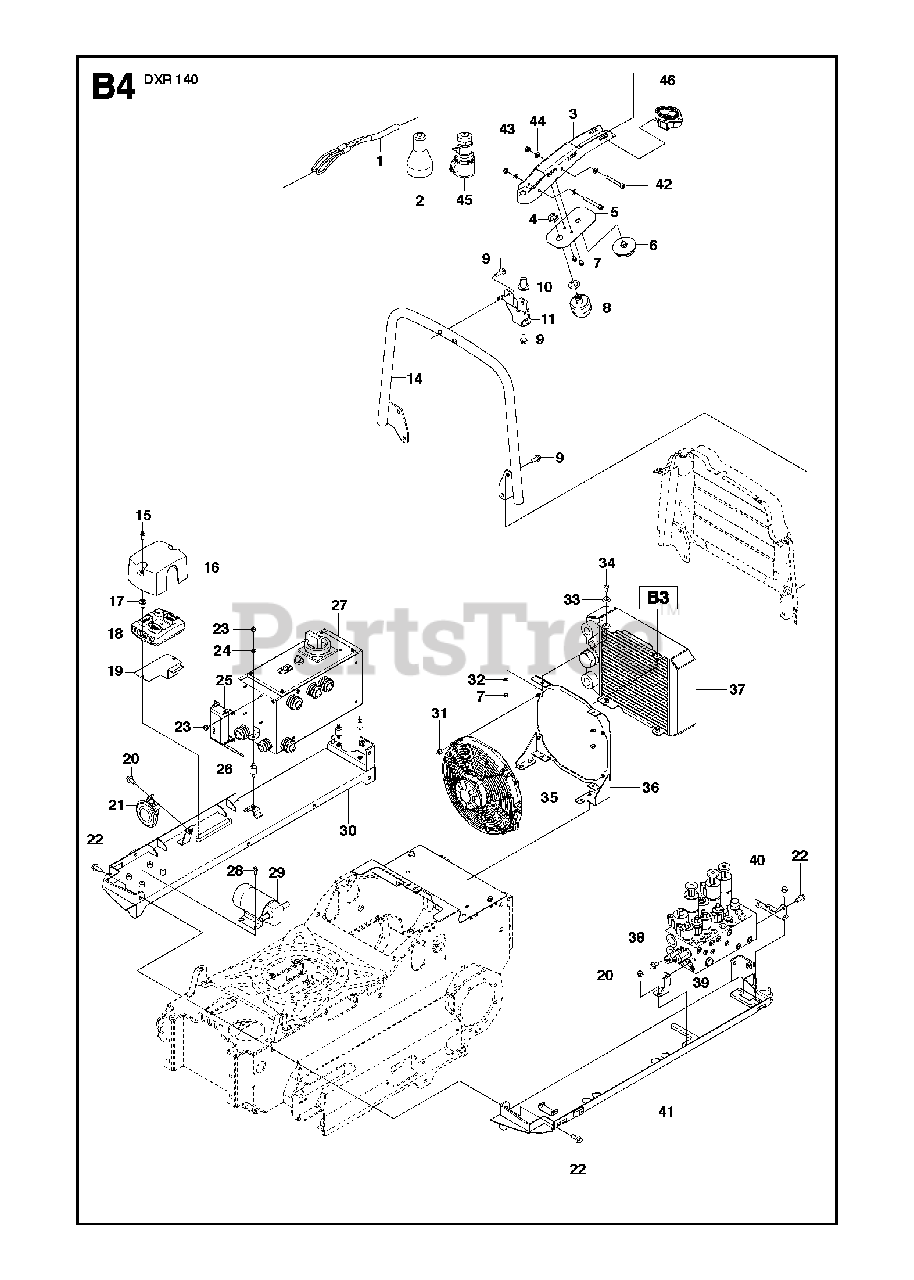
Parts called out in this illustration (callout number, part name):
23	HEXAGON LOCKING NUT
29	OIL PUMPValid for machine S/N 255-forward
29	OIL PUMPValid for machine S/N 1-254
34	SCREW IHCSFM
38	VALVE ASSYValid for machine S/N 1-254
38	VALVE ASSYValid for machine S/N 255-forward
